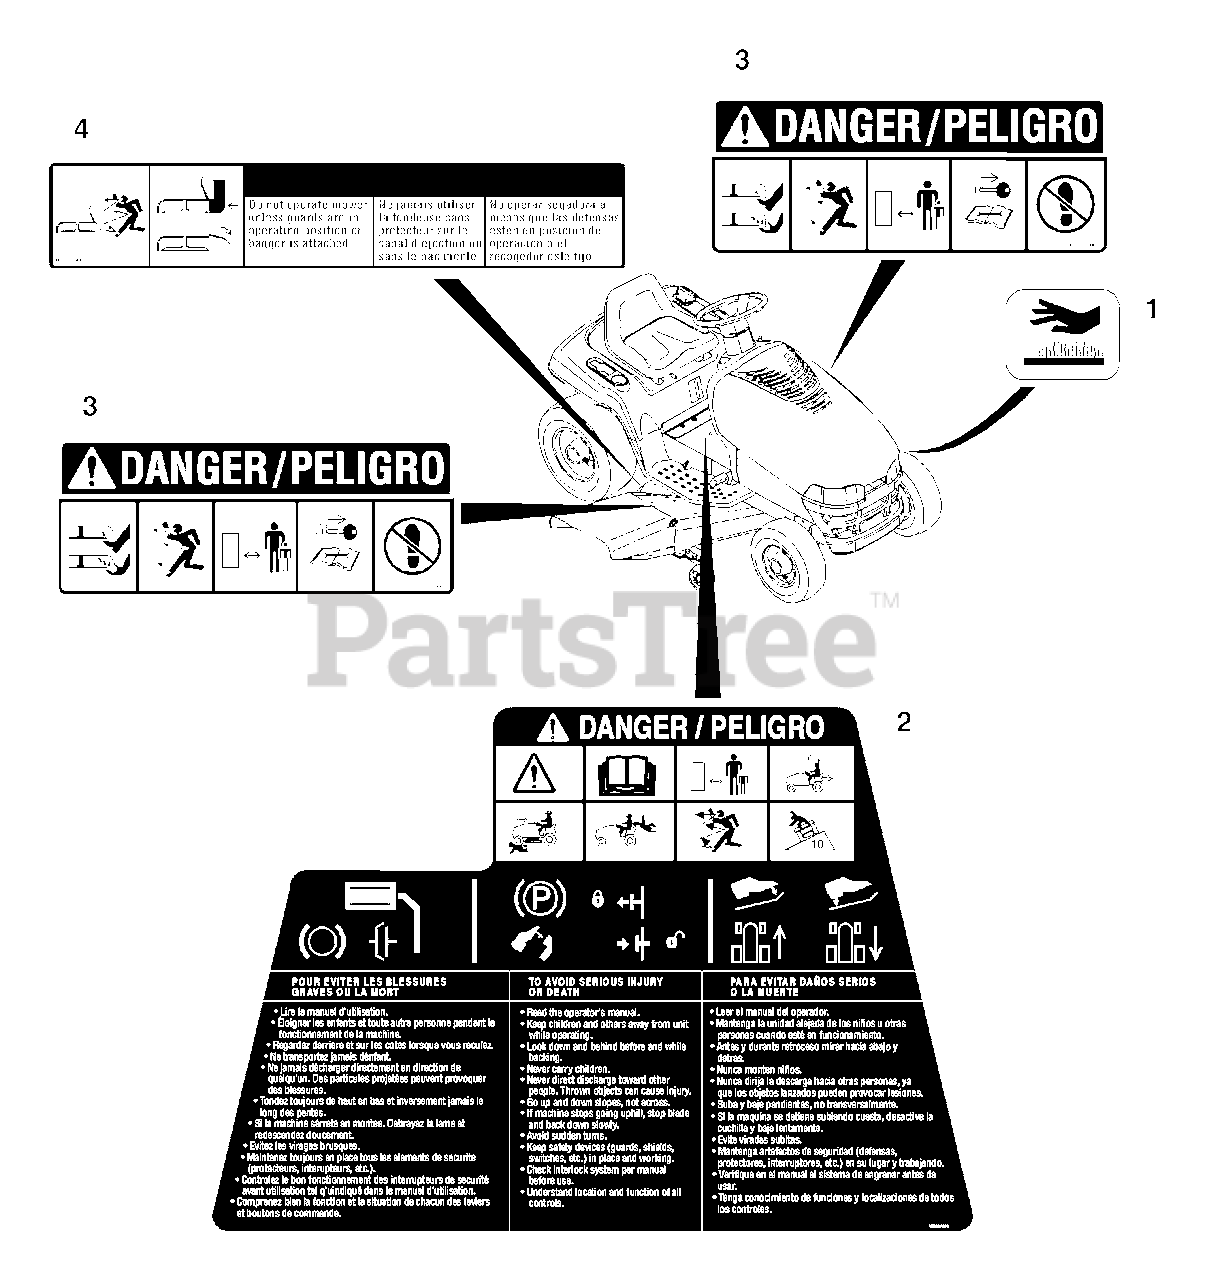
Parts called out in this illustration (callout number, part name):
1	DECAL, HOT SURFACE
2	DECAL OPERATING INSTRUCTIONS
3	DECAL, MOWER PAN DANGER
4	DECAL, WARNING
